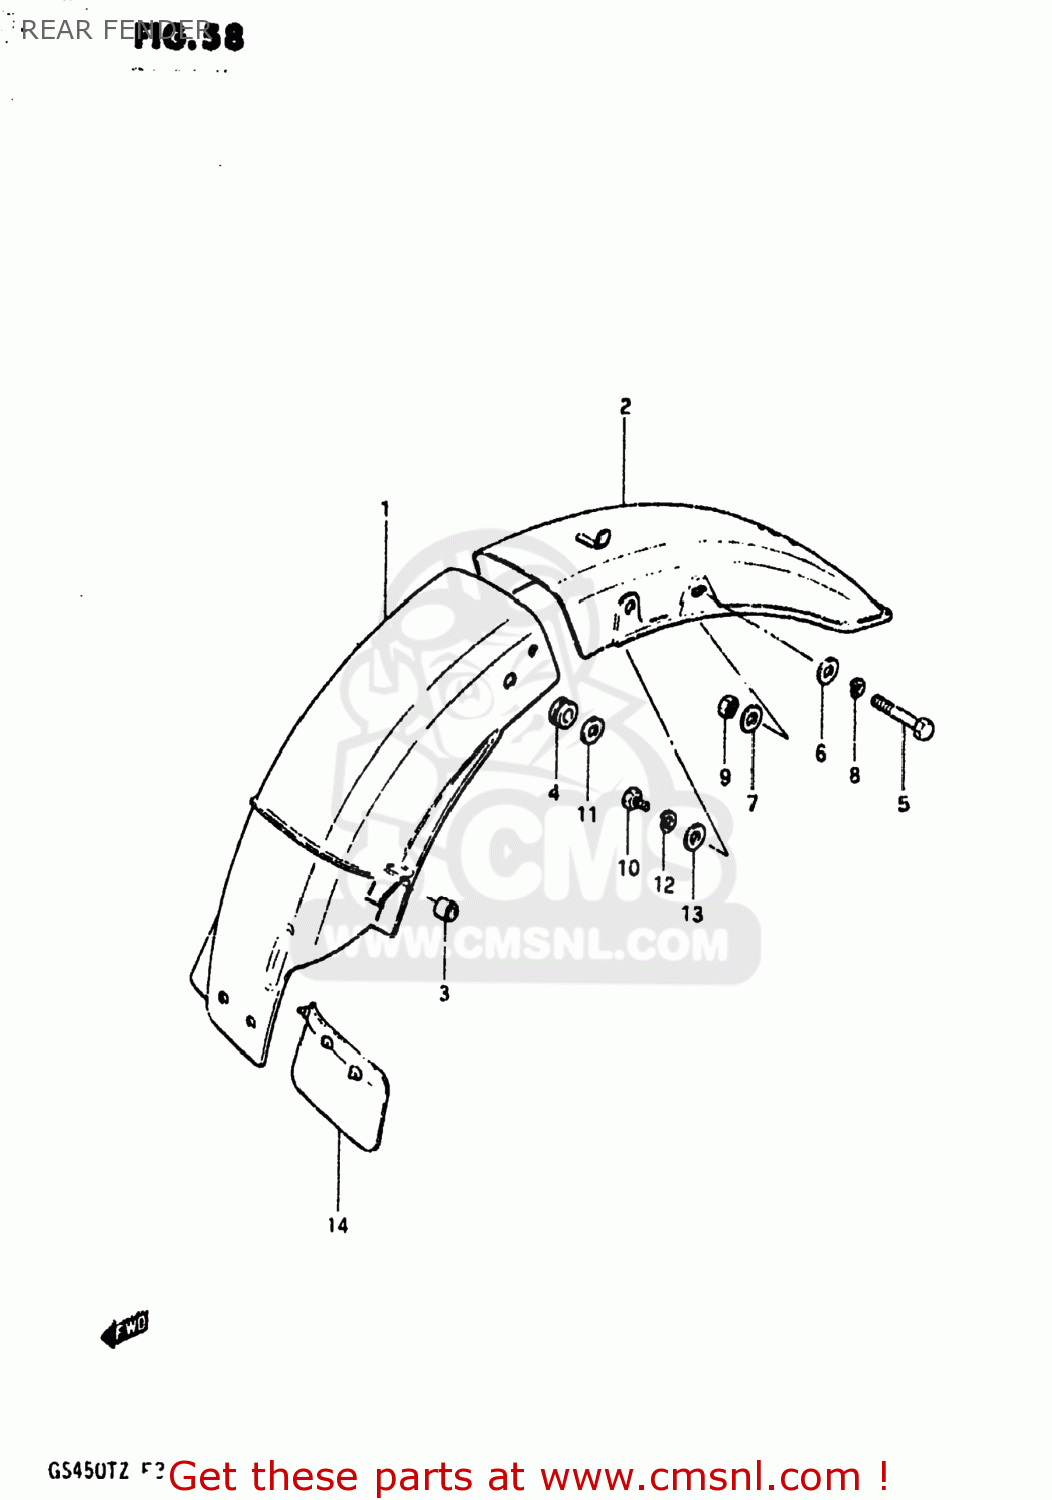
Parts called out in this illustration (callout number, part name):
1	FENDER,REAR
2	FENDER,REAR
3	CUSHION
4	CUSHION
5	BOLT 8X100
6	WASHER
7	WASHER
8	LOCK WASHER
9	NUT
10	BOLT 8X12
11	WASHER
12	LOCK WASHER
13	WASHER
14	GUIDE,RR FENDER MUD
